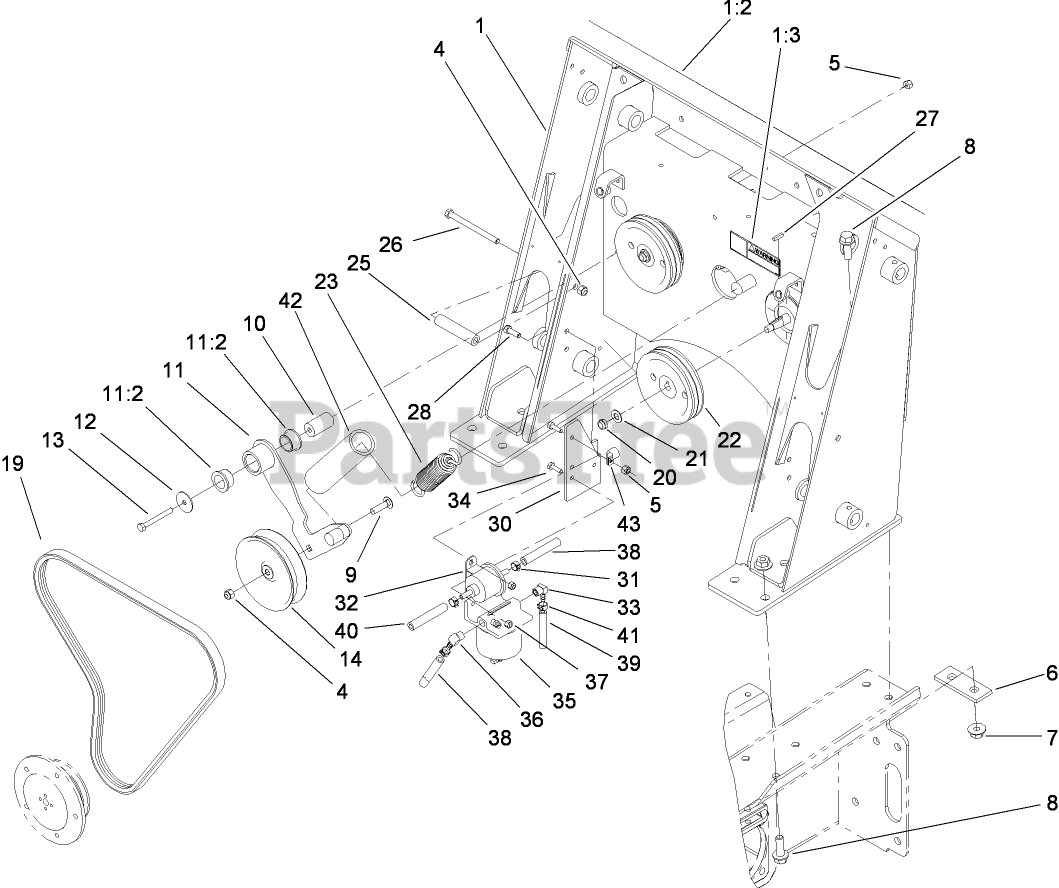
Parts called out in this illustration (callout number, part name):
1	LOADER TOWER ASM
1:2	DECAL-PANEL, CONTROL
1:3	DECAL-WARNING
4	NUT-LOCK, NI
5	NUT-LOCK, NI
6	PLATE-STIFFENER
7	NUT-LOCK, FLANGE
8	SCREW-HHF
9	SCREW-CARR
10	SPACER-MOUNTING
11	IDLER ARM ASM
11:2	BUSHING-FLANGE
12	WASHER-FLAT
13	SCREW-HH
14	PULLEY-IDLER
19	V-BELT
20	NUT-LOCK, NI
21	WASHER-FLAT
22	PULLEY
23	SPRING-EXTENSION
25	TUBE-SPACER
26	SCREW-HH
28	SCREW-HH
30	BRACKET-PUMP, FUEL
31	CLAMP-HOSE
32	PUMP-FUEL, ELECTRIC
33	ELBOW
34	SCREW-HH
35	SEPARATOR-FILTER / WATER
36	FITTING-ELBOW
37	NUT-LOCK, NI
38	HOSE-LP
39	HOSE-FUEL
40	HOSE-FUEL
41	CLAMP-HOSE
42	RETAINER-SPRING
43	CLAMP-R
